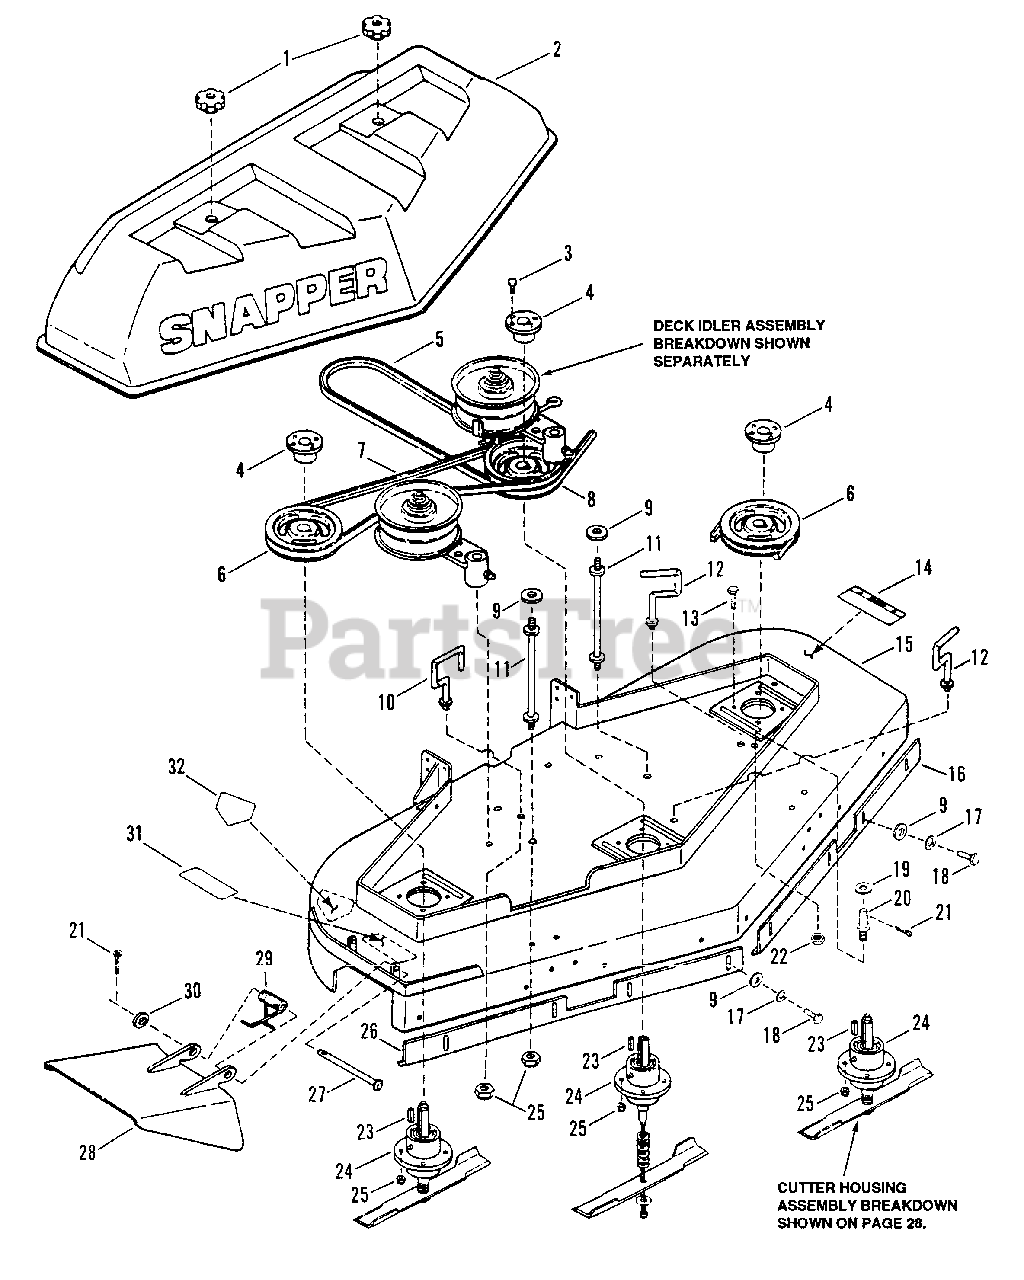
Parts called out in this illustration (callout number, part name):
1	KNOB, Hood
2	HOOD, 48" Silver
3	BOLT, 1/4-20 x 7/8" Hex Head Cap
4	BUSHING, Taperlock
5	BELT, Engine/Deck 48"
6	PULLEY, Single
7	BELT, Blade - Blade, 48"
8	PULLEY, Double
9	WASHER, 13/32 I.D. x 1 1/2 O.D.
10	GUIDE, Belt
11	STUD, Hood
12	GUIDE, Belt
13	SCREW, 3/8 x 1 1/4 HHC
14	DECAL, Caution
15	DECK WELDMENT, 48"
16	SKIRT, Front, Left Hand
17	WASHER, 3/8 Lock
18	SCREW, 3/8 - 16 x 3/4 HHC
19	WASHER, 3/8" Flat
20	STUD, Clutch Link
21	COTTER PIN
22	NUT, 3/8 - 24 Hex Lock
23	KEY, Spindle
24	ASSEMBLY, Cutter Housing
25	NUT, 3/8 - 16 Nyloc
26	SKIRT, Front, Right Hand
27	ROD, Chute Pivot
28	DEFLECTOR, 48" Chute
29	SPRING, Chute
30	WASHER, 5/16 SAE Flat
31	DECAL, Caution
32	DECAL, Warning
